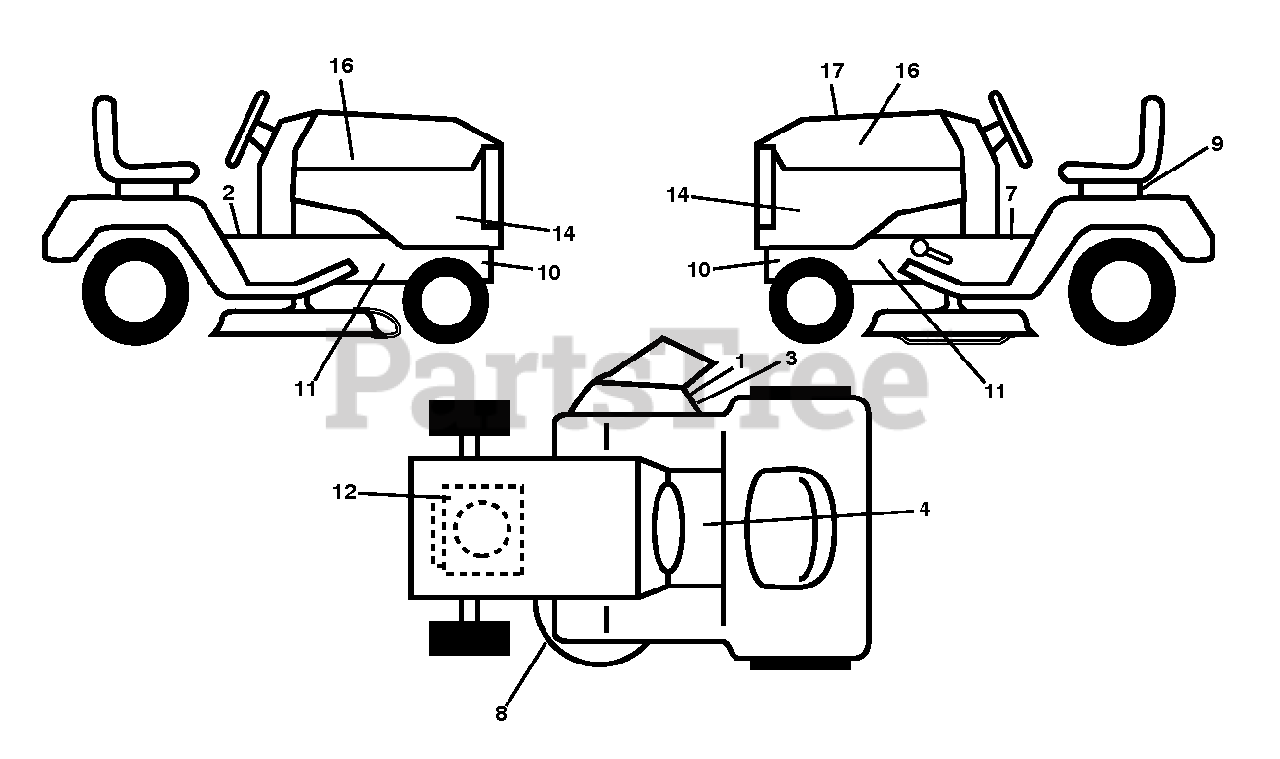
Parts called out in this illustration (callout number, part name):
1	DECAL.CUTFINGER.CE.02
2	DECAL.READ.OWN.MAN.SYMBOL.LT
3	DECAL.DFLCTR.WARNNG.CTFNGR.SYM
4	DECAL.PARKING.BRAKE.SADDLE.LT
7	DECAL.FNDR.SDLE.BRAKE.CLUTCH.6
8	DECAL.V-BELT.SCH.42/46"MEC/ELE
9	DECAL BTRY SYMBOLS
10	DECAL.CHASSIS.HOT.MUFFLER
11	DECAL.WARNING.SERVCE/FIRE
12	DECAL.ENGINE.WARNING
16	DECAL.BADGE.170MM.TEXTLOGO.
